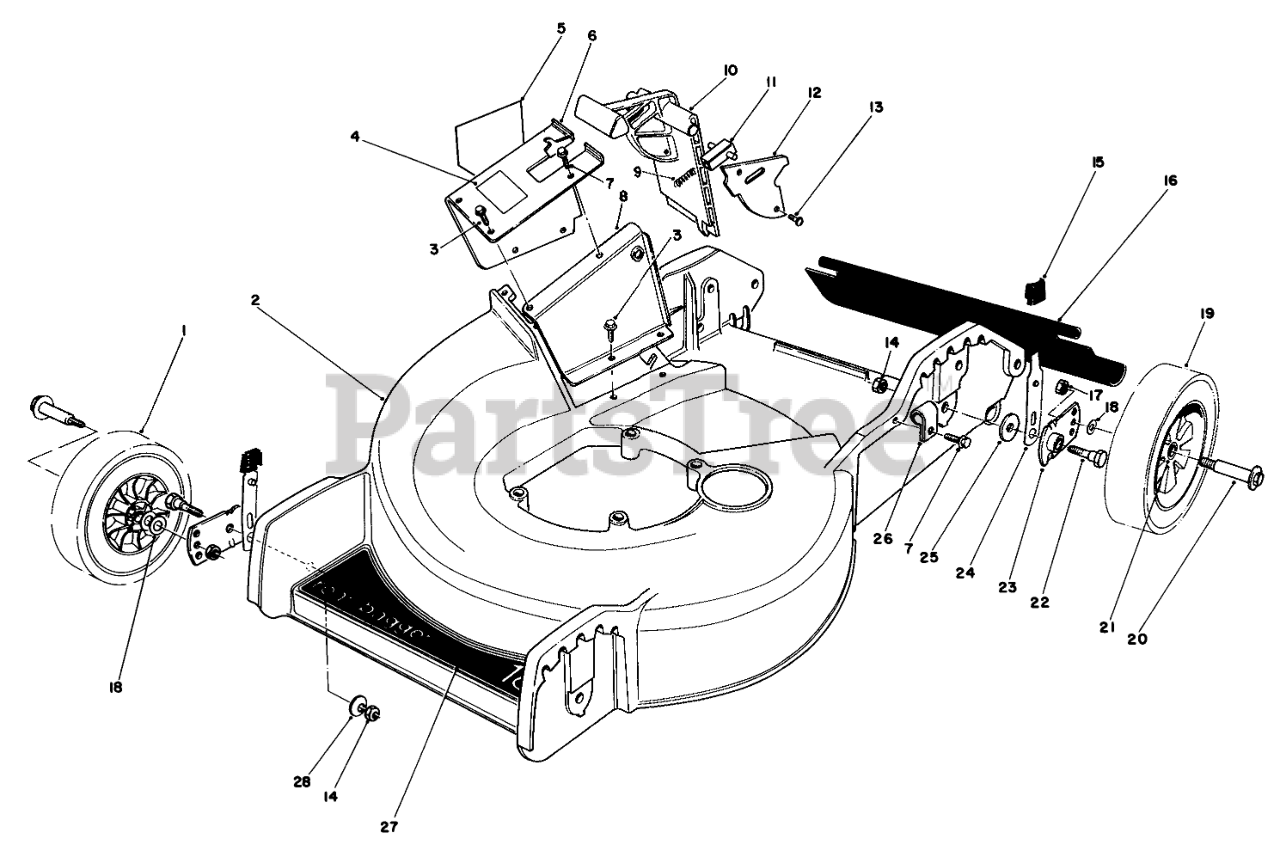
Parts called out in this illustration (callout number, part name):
1	Wheel & Tire Assembly (Incl. Ref. #21)
2	Housing
3	SCREW
4	Decal-Door
5	DECAL-DANGER
6	Tunnel-Outer
7	SCREW
8	Tunnel-Inner
9	SPRING-COMPRESSION, LATCH
10	Door Mulching
11	Door Latch
12	Cover Door
14	NUT-LOCK, NI
15	KNOB-ARM
16	SHIELD - TRAILING
17	Nut
18	WASHER
19	Wheel & Tire Assembly (Incl. Ref. #21)
20	BOLT-WHEEL
21	BUSHING
22	5/16-18 PIVOT SCREW
23	PIVOT ARM ASSY
24	SPRING ARM ASM
25	PIVOT WASHER
26	CLAMP-NYLON
27	DECAL-DECK
28	WASHER-BELLEVILLE
